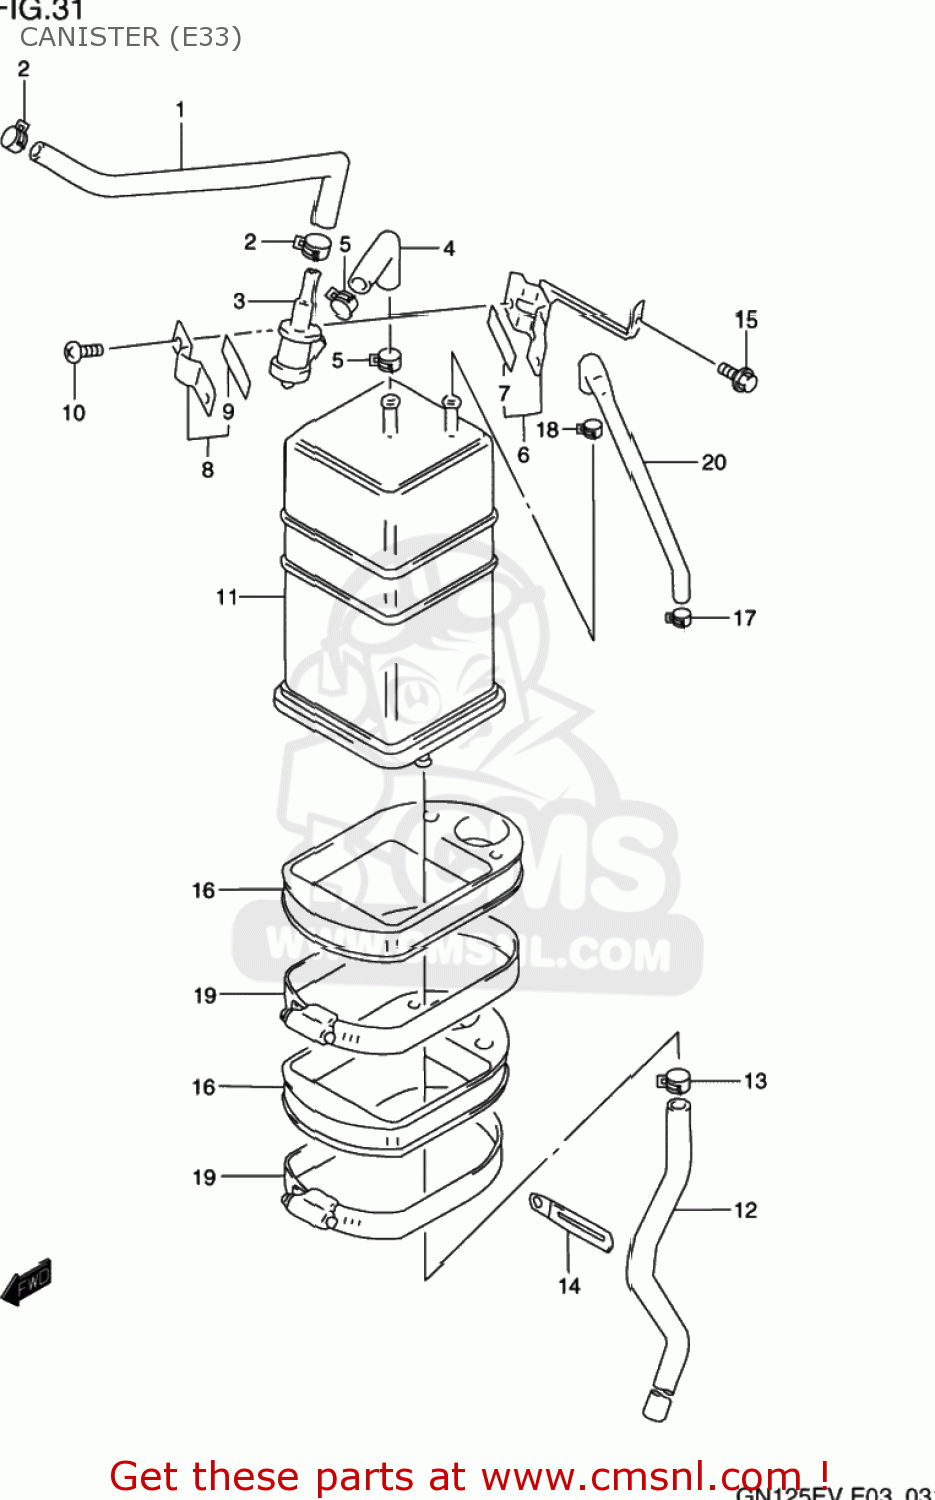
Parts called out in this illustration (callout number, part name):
1	HOSE,TANK & BREATHER VALVE
2	CLIP
3	VALVE,FUEL TANK BREATHER
4	HOSE,BREATHER VALVE & CANISTER
5	CLIP
6	PLATE COMP,TANK BREATHER
7	CUSHION
8	PLATE,FUEL TANK BREATHER NO.2
9	CUSHION
10	SCREW
11	(CA) CANISTER ASSEMBLY
12	HOSE(7X12X600)
13	CLIP
14	CLAMP(L:45)
15	BOLT
16	CUSHION,CANISTER
17	CLIP
18	CLIP
19	CLAMP
20	HOSE(3.5X7.5X600)
